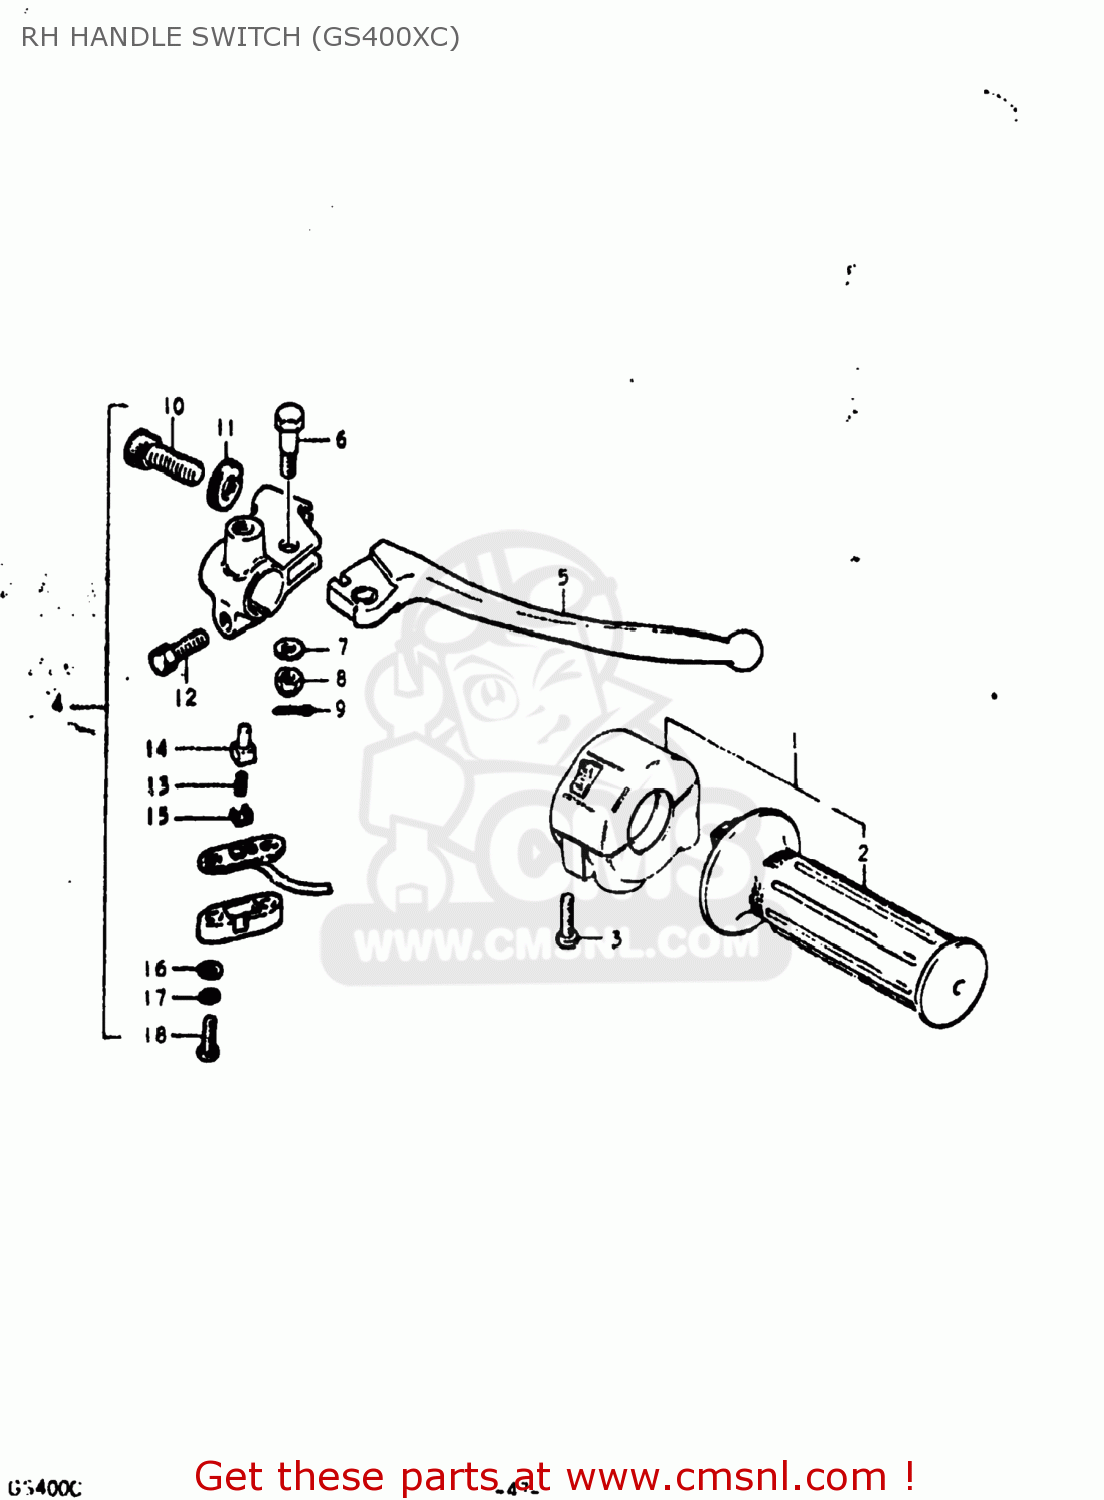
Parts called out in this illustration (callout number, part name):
1	CASE ASSEMBLY,THROTTLE
2	GRIP,THROTTLE
3	SCREW
4	LEVER ASSEMBLY,BRAKE
5	LEVER,BRAKE
6	BOLT,LEVER
7	LOCK WASHER
8	NUT,LEVER FITTNG
9	COTTER PIN
10	ADJUSTER,CABLE
11	NUT,CABLE ADJUSTER
12	BOLT
13	SPRING
14	HOLDER
15	PLATE
16	WASHER
17	LOCK WASHER
18	SCREW
